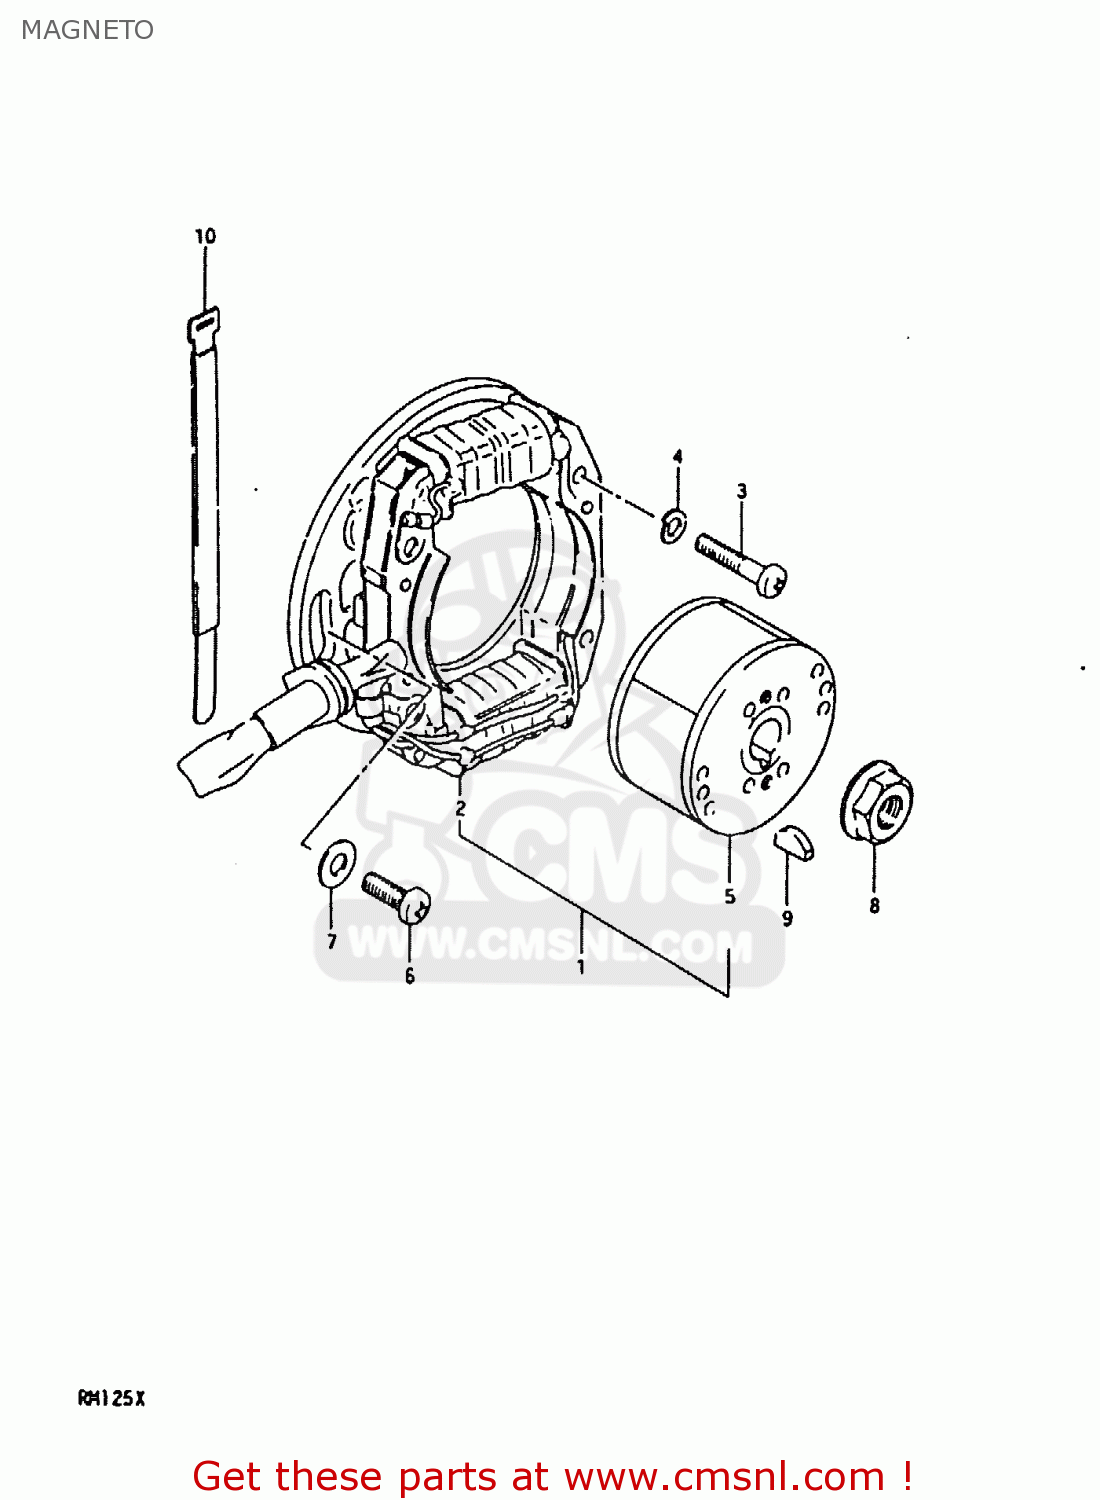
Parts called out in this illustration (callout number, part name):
1	MAGNETO ASSEMBLY
2	STARTER ASSY
3	SCREW 5X20
4	LOCK WASHER
5	ROTOR ASSEMBLY
6	SCREW
7	WASHER
8	NUT
9	KEY 4MM
10	CLAMP
